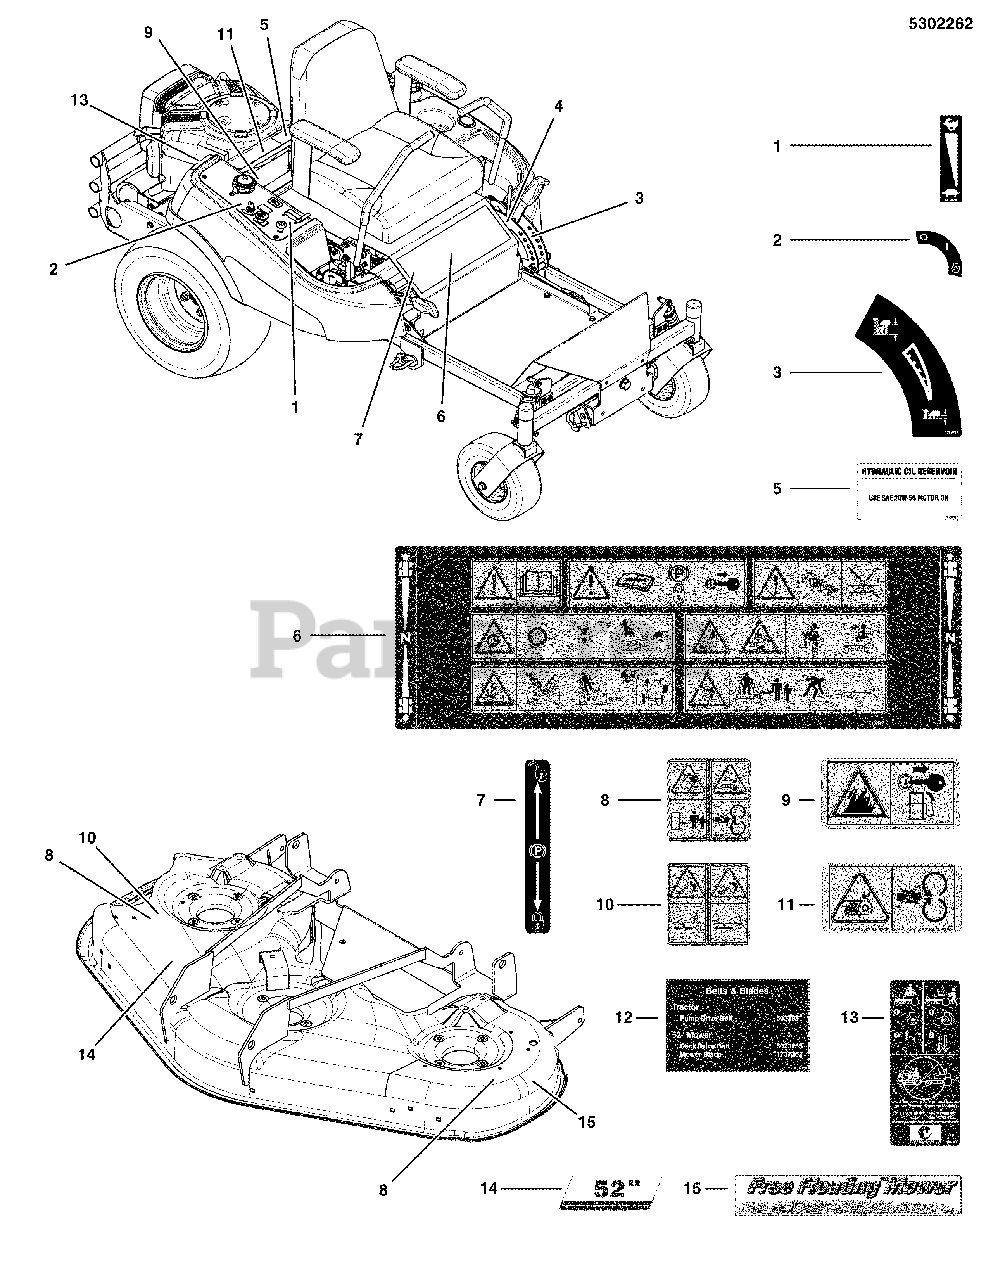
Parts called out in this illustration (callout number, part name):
1	DECAL, THROTTLE CONTROL
2	DECAL, IGNITION SWITCH
3	DECAL, HEIGHT OF CUT
4	* DECAL, US PATENT, ZTR
5	DECAL, HYDRAULIC OIL, SAE 20W50
6	DECAL, MAIN SAFETY, ANSI CE
7	DECAL, PARKING BRAKE SYMBOLS
8	DECAL, DANGER, MOWER DECK, ANSI EXP
9	DECAL, FIRE ANSI EXPORT
10	DECAL, DANGER DISCHARGE ANSI EXPORT
11	DECAL, CE DANGER
12	DECAL, BELT & BLADE, CHAMP, 52
13	DECAL, CZT HYRDO RELEASE
14	DECAL-52"-SILVER ON BLACK W/STRIPE
15	DECAL-FREE FLOATING MOWER- SILVER
